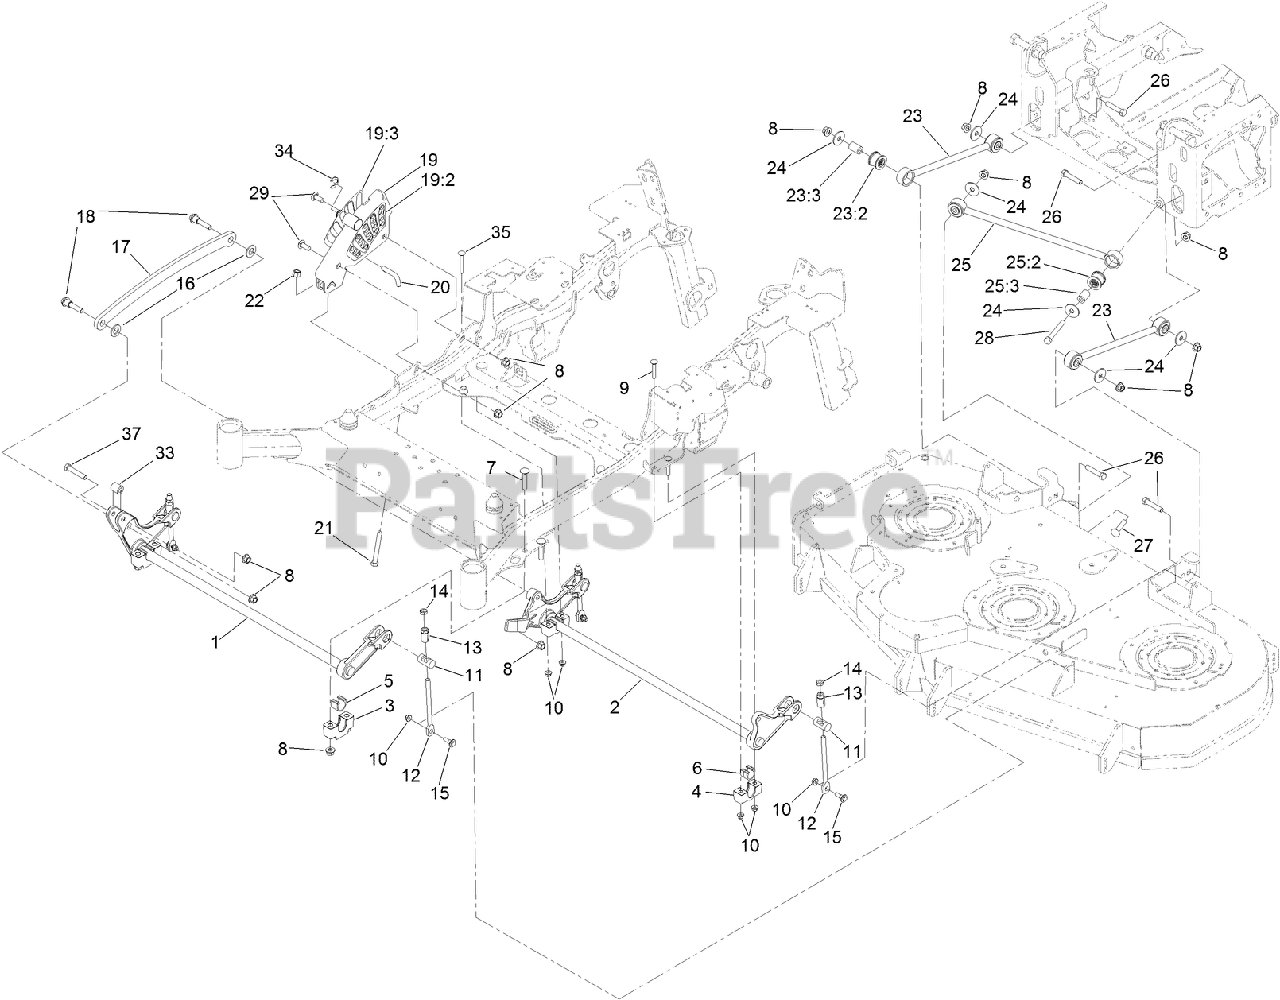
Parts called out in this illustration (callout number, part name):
1	DECKLIFT-FRONT
2	LIFT-DECK, REAR
3	SUPPORT-CROSS SHAFT, BEARING
4	SUPPORT-CROSS SHAFT, BEARING REAR
5	BEARING-CROSS SHAFT, FRONT
6	BEARING-CROSS SHAFT, REAR
7	BOLT-CARR
8	NUT-LOCK
9	SCREW-HH
10	NUT-HF, NI
11	TRUNNION
12	LINK-ADJUSTER, DECK LIFT
13	ADJUSTER-LIFT, DECK
14	NUT-JAM
15	SCREW-SHOULDER, HHF
16	WASHER-FLAT
17	LINK-LIFT, DECK
18	SCREW-HHF, SHOULDER
19	HOC ASM
19:2	DECAL-HEIGHT OF CUT
19:3	DECAL-HEIGHT OF CUT, OUTER
20	PIN-HOC
21	BOLT-TAP
22	NUT-LOCK, NI
23	DECK STRUT ASM
23:2	BUSHING-SUSPENSION, RUBBER
23:3	SPACER
24	WASHER-THRUST
25	PANHARD ROD ASM
25:2	BUSHING-SUSPENSION, RUBBER
25:3	SPACER
26	SCREW-HH
27	SCREW-CARR
28	SCREW-HH
29	SCREW-CARR, SHORT NECK
33	SPACER-PIVOT
34	RING-RETAINING
35	SCREW-HH
37	SCREW-HH
